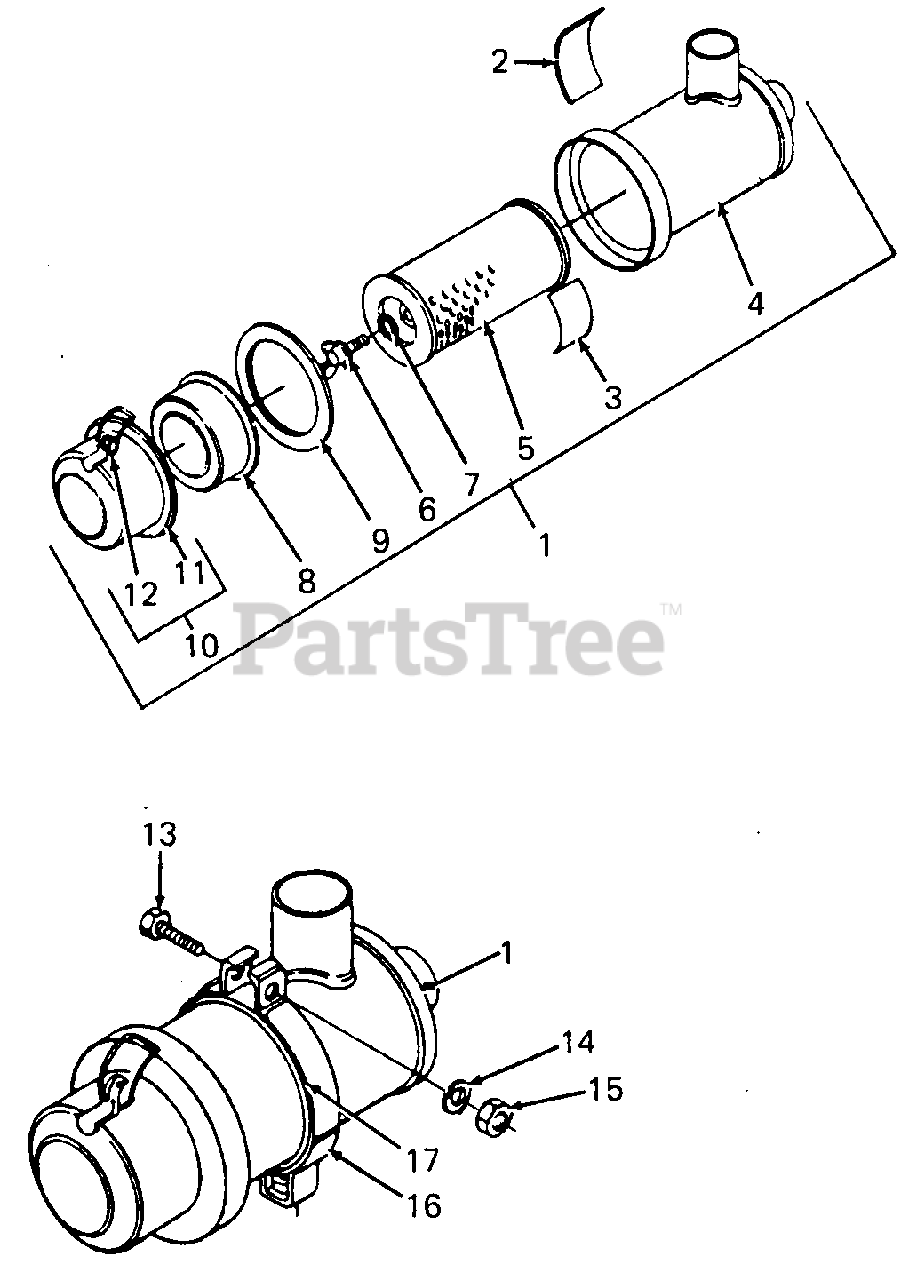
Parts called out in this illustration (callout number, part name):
1	Cleaner Assy, Air
2	Label - Not Serviced Separately
3	Label - Not Serviced Separately
4	Body Assy, Air Cleaner
5	Element, Air Cleaner
9	Gasket, Air Cleaner Cover
10	Cover, Air Cleaner
13	Screw, Hex Cap
14	Washer, Spring
16	Band, Air Cleaner
